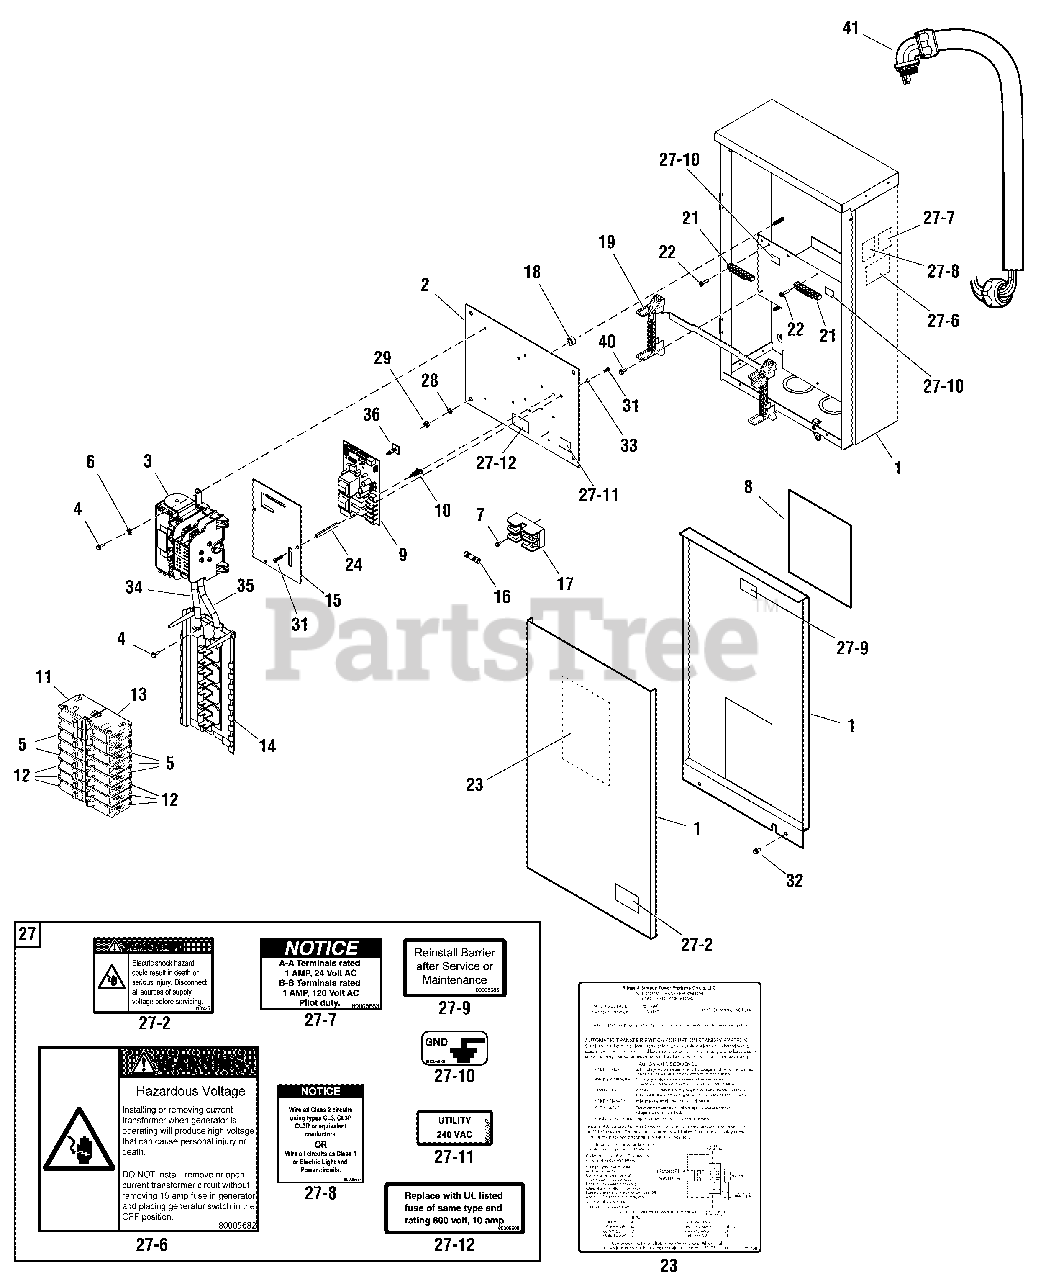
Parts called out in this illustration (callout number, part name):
1	ENCLOSURE
2	BACK PANEL
3	SWITCH-TRANSFER
4	* TRILOBULAR, #10-32 x 1/2
5	BREAKER-CIRCUIT, 20A
6	* WASHER, External Tooth, #10
7	* SCREW, Hex Head, Trilobular, #6-32 x 3/8
9	BOARD-CIRCUIT
11	BREAKER-CIRCUIT, 20A
12	BREAKER-CIRCUIT, 15A
13	BREAKER-CIRCUIT, 30A
18	SPACER
19	BLOCK-NEUTRAL
21	BAR, Ground
22	* TRILOBULAR, #10-32 x 3/4
27	DECAL SHEET-WARNINGS
27-2	DECAL-WARNING, ELECTRIC SHOCK
27-6	DECAL-CT NOTICE
27-7	DECAL-CONTACTS RATED NOTICE
27-8	DECAL-WIRE CIRCUITS
27-9	DECAL-REINSTALL AFTER
27-10	DECAL-GROUND
27-11	DECAL-UTILITY, 240VAC
27-12	DECAL-FUSE
28	* WASHER, Lock, 1/4
29	* NUT, 1/4-20
31	* SCREW, Phillips, 6-32 x 3/8
32	* TRILOBULAR, #10-32 x 3/8
33	* WASHER, Lock, #6
40	* TRILOBULAR, #10-31 x 3/4
41	WHIP ASSEMBLY
